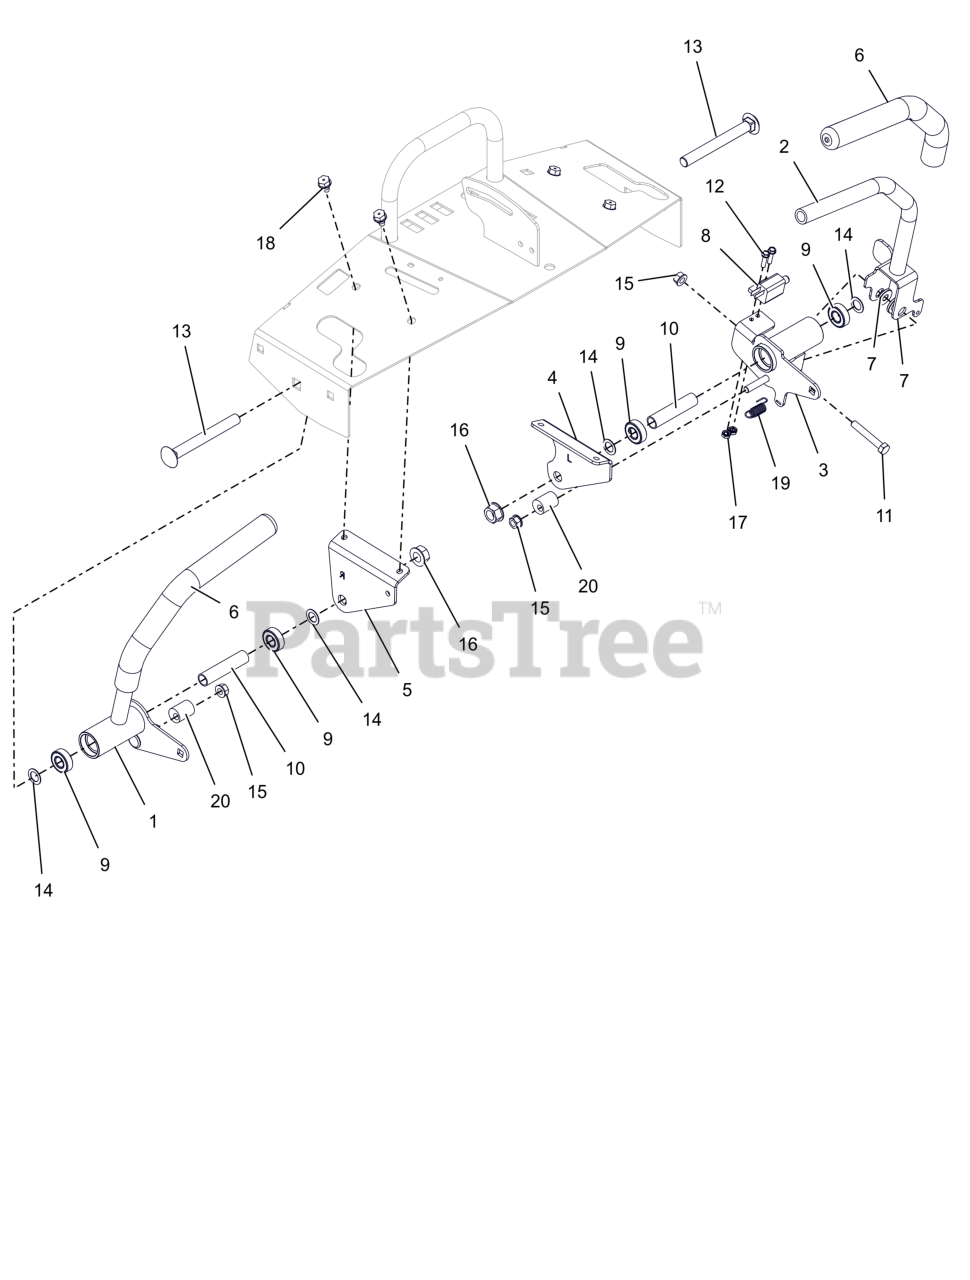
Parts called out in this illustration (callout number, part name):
1	WLDMT, RH DRIVE CONTROL (BLACK)
2	WLDMT, LH HANDLE ASM (BLACK)
3	WLDMT, LH DRIVE CONTROL (BLACK)
4	BRKT, LH DRIVE CONTROL MTG
5	BRKT, RH DRIVE CONTROL MTG
6	GRIP, HANDLEBAR
7	BSHG, FLG .325X.499X.26X.88
8	SWITCH- SINGLE POLE N.O.
9	BEARING, .500X1.125X.375
10	SPCR, .510 X .625 X 2.75
11	BLT, HEX .31-18X2.00 G5 ZCC
12	BLT, HWH #10-24X.75 ZCC
13	BLT,RHSN .50-13X4.50 G5 ZCC
14	WSHR-FL-STL 0.52X0.81X0.033 ZCC
15	NUT,LK-CTR-FLG .31-18 GF ZCC
16	NUT-LK-CTR-FLG .500-13 GG ZCC
17	NUT-KEPS 10-24
18	SCR,TAP .312-18X.50 HWH TR ZCC
19	SPRING, EXT. .043X.438X1.64
20	ECCENTRIC
